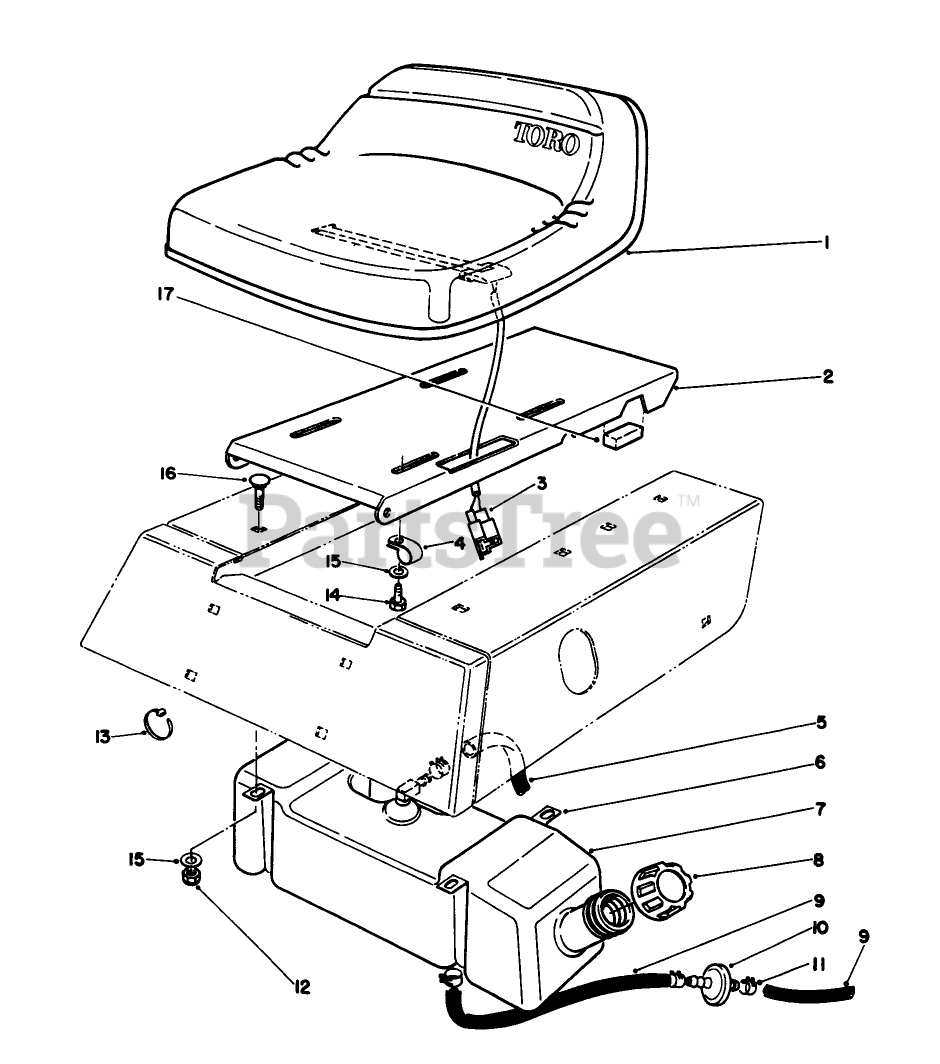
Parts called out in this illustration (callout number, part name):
2	BASE - SEAT *
3	SWITCH-SEAT
4	CLIP-FUEL LINE
6	STRAP-GAS TANK
7	TANK-GAS
8	GAS CAP ASM
10	FILTER-FUEL
11	CLAMP-HOSE
12	NUT-LOCK, NI
13	TIE-CABLE
14	SCREW-HH
15	WASHER-PLAIN
17	PAD-ISOLATOR
